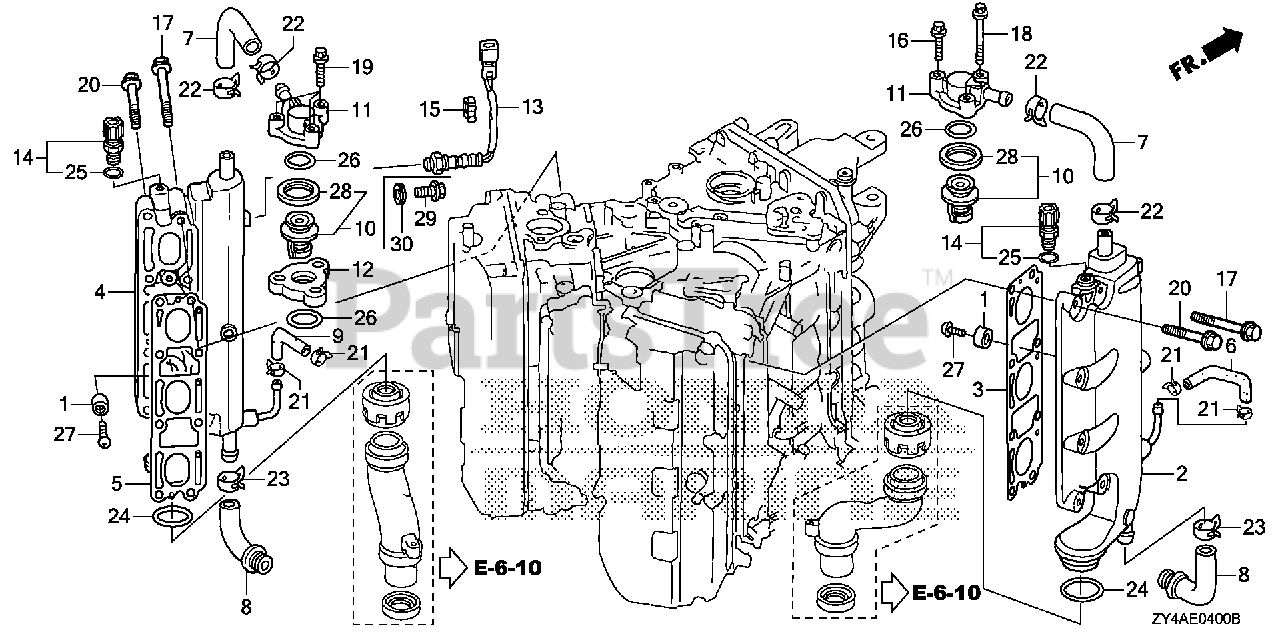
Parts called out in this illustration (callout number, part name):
1	METAL, ANODE
2	MANIFOLD, R. EX. *NH8* (DARK GRAY)
3	GASKET, R. EX. MANIFOLD
4	MANIFOLD, L. EX. *NH8* (DARK GRAY)
5	GASKET, L. EX. MANIFOLD
6	TUBE, R. WATER RETURN
7	TUBE, WATER RELIEF
8	TUBE, WATER
9	TUBE, L. WATER RETURN
10	THERMOSTAT ASSY.
11	COVER, THERMOSTAT *NH8* (DARK GRAY)
12	SPACER, THERMOSTAT *NH8* (DARK GRAY)
14	SENSOR ASSY., WATER TEMPERATURE
16	BOLT, FLANGE (6X35)
17	BOLT, FLANGE (8X60)
18	BOLT, FLANGE (6X60)
19	BOLT, FLANGE (6X50)
20	BOLT, FLANGE (8X40)
21	CLAMP, TUBE (D10.5)
22	CLAMP, TUBE (D29)
23	CLAMP, TUBE (D21)
24	O-RING (66.4X3.1)
25	O-RING (9.5X1.9)
26	O-RING (31.5X2.4) (ARAI)
27	SCREW, PAN (6X18)
28	RUBBER, RING
29	BOLT, FLANGE (10X20)
30	WASHER, SEALING
